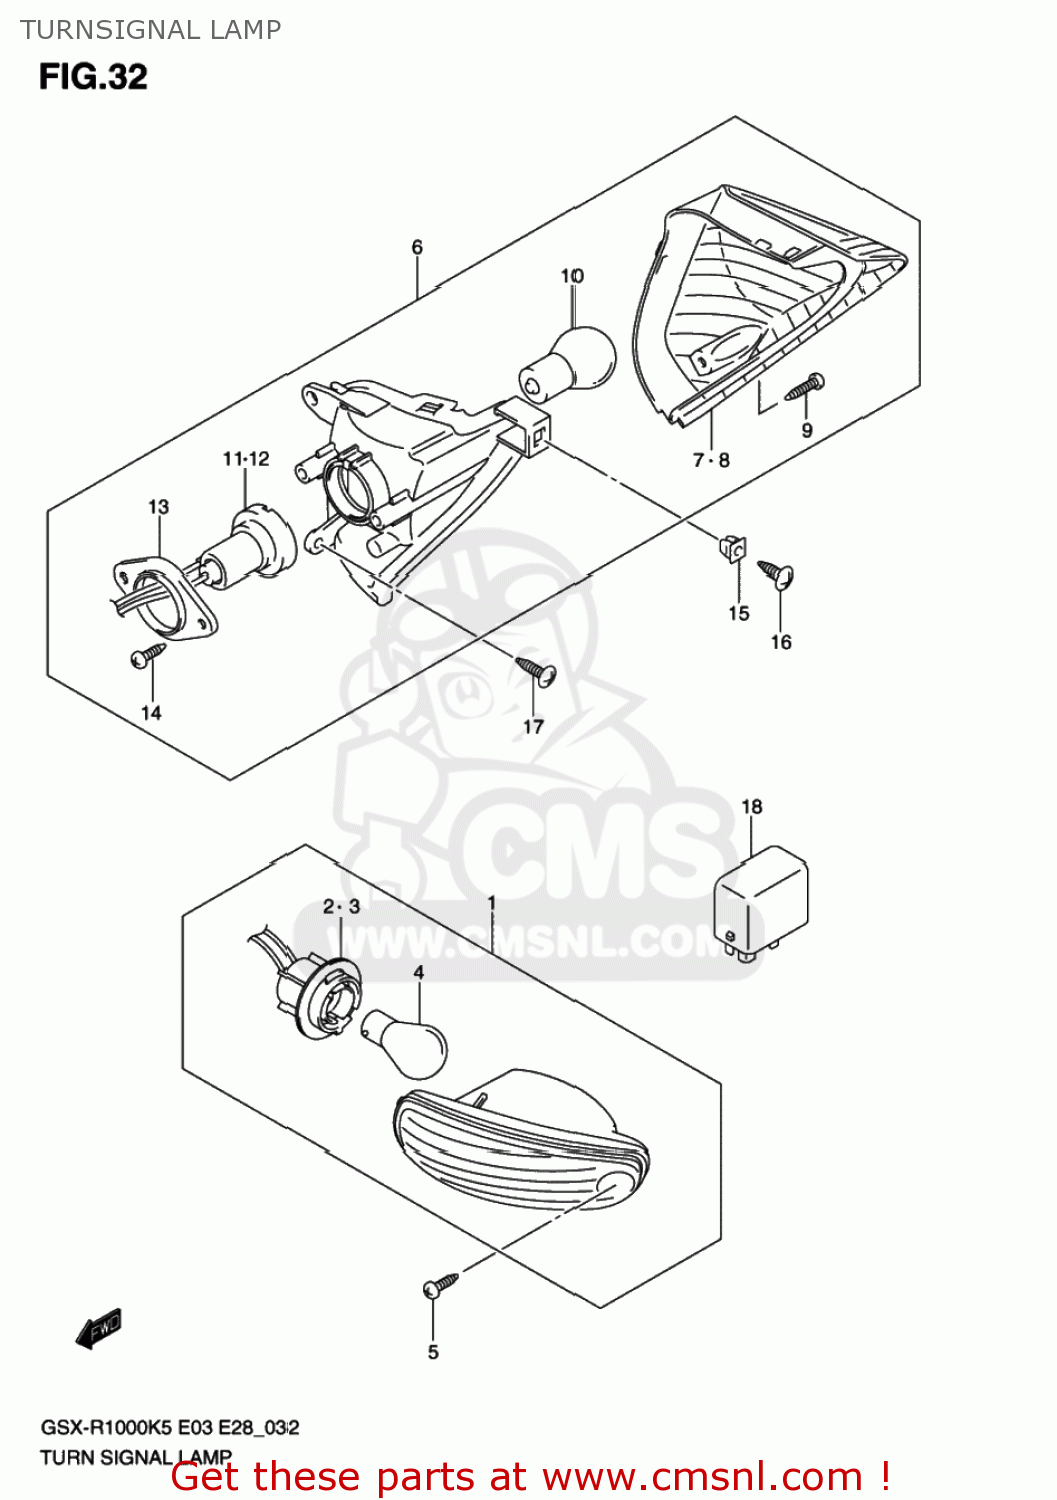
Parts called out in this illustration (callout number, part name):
1	LAMP ASSY,FR TURN SIGNAL,R
2	SOCKET,R
3	SOCKET,L
4	BULB(12V21W,AMBER)
5	SCREW(4X20)
6	LAMP ASSY,REAR
7	LENS,R
8	LENS,L
9	SCREW
10	BULB(12V21W,AMBER)
11	SOCKET & CORD,R
12	SOCKET & CORD,L
13	PLATE,RR COMBINATION
14	SCREW
15	NUT
16	SCREW
17	SCREW
18	RELAY ASSY,TURNSIGNAL LAMP
